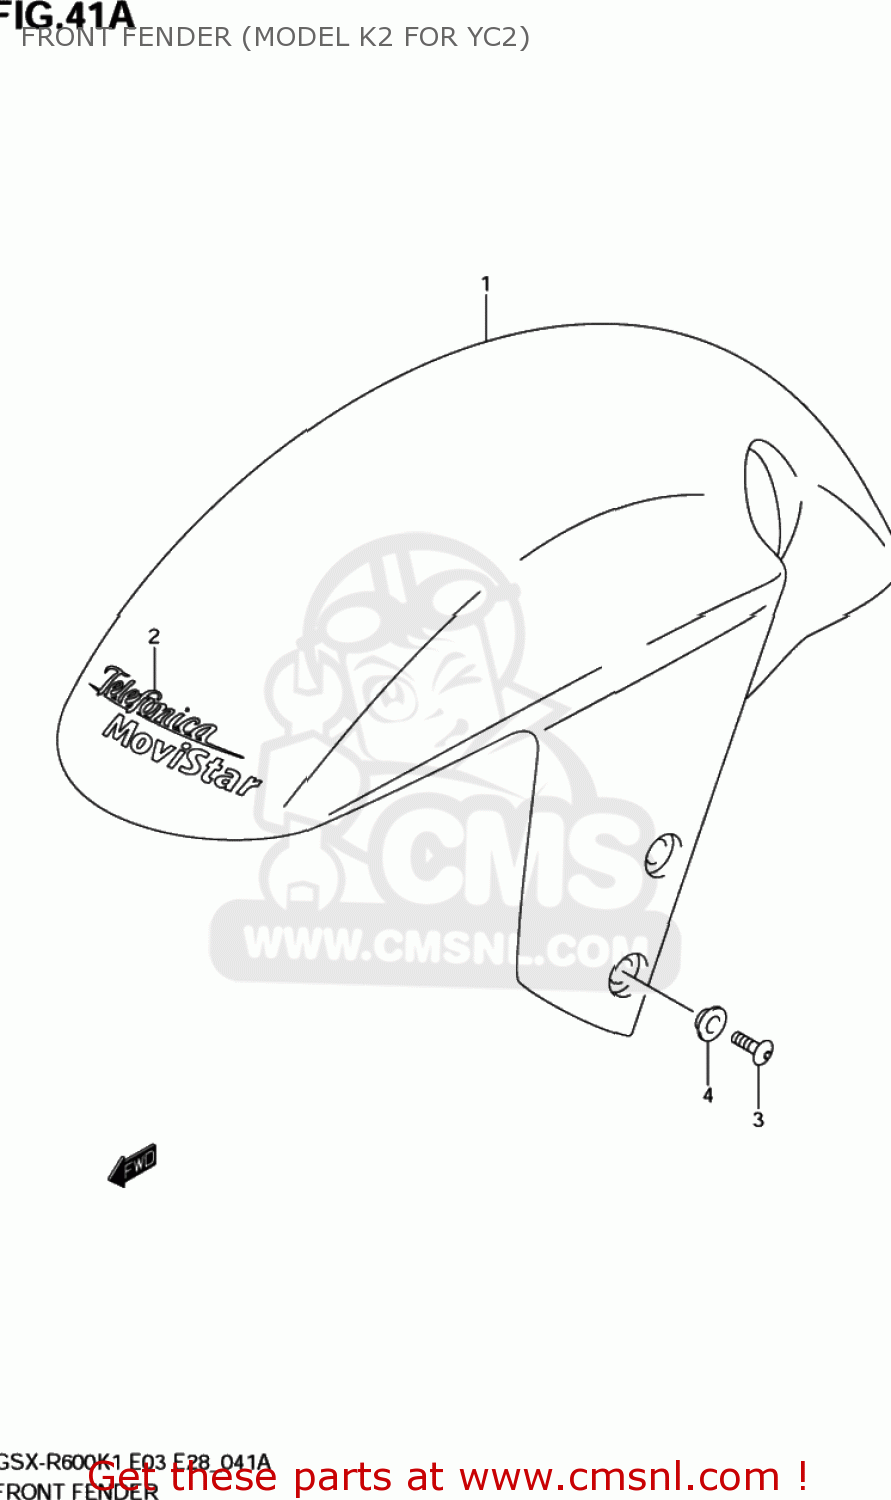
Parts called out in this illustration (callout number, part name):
1	FENDER ASSY,FR(BLUE)
2	EMBLEM,FR FENDER
3	SCREW(6X16)
4	WASHER(6.3X16X1.5)
